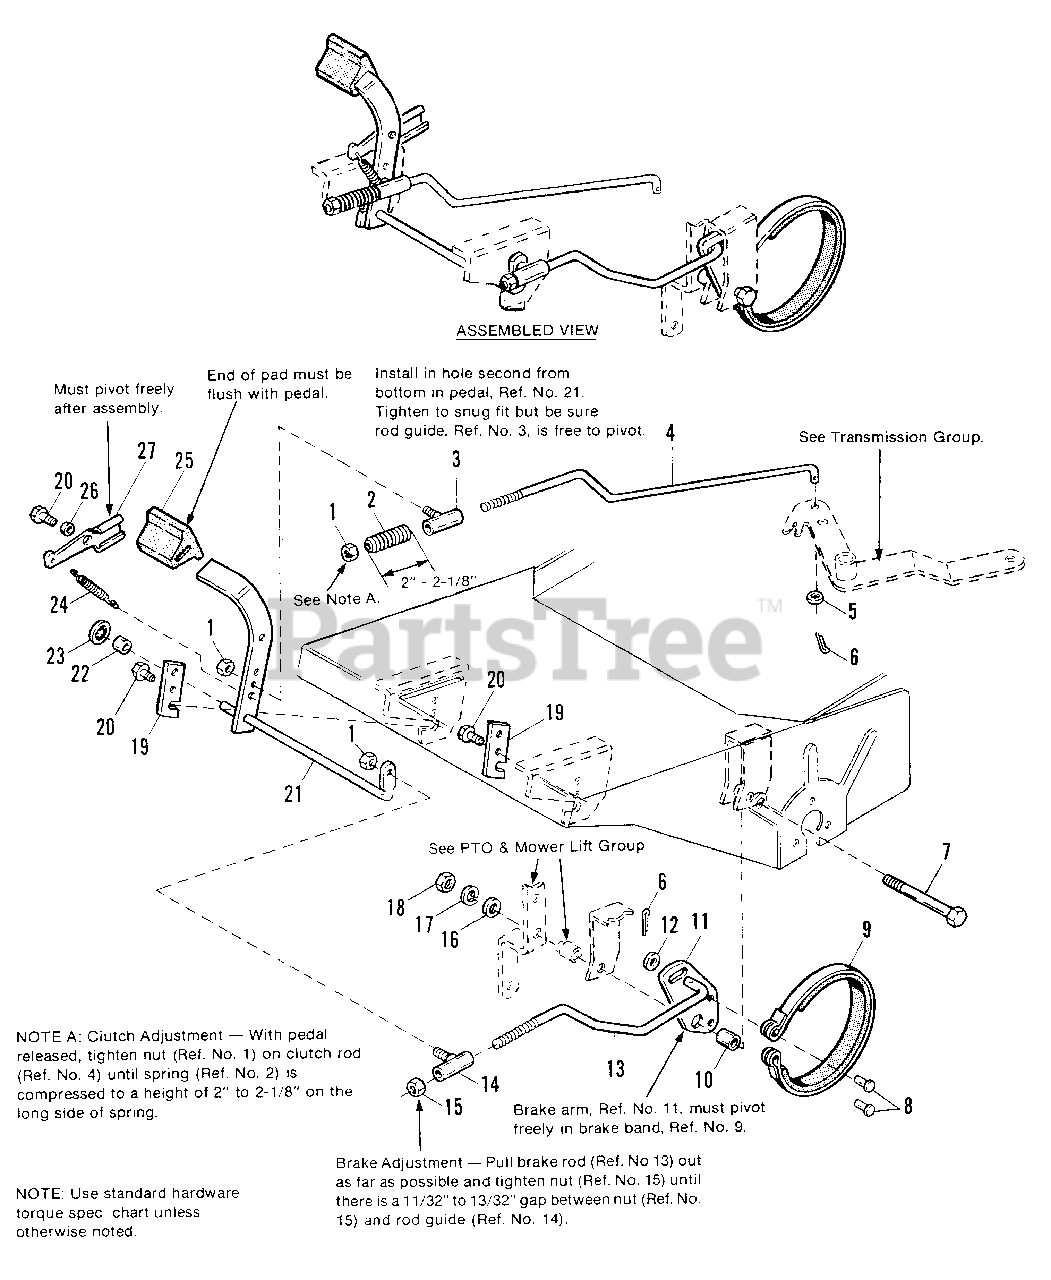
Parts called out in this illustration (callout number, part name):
1	NUT, Hex Lock, 5/16-18
3	GUIDE ASSY., Rod
4	ROD, Clutch
5	WASHER, 11/32 x 3/4
6	PIN, Cotter, 3/4
7	CAPSCREW, 1/2-13 x 3-1/2, Gr. 5
9	BAND ASSY., Brake
11	LINK, Brake Arm
12	WASHER, 3/8
13	ROD, Brake
14	GUIDE ASSY., Rod
15	NUT, Hex Lock, 3/8-16
16	WASHER, 1/2
17	LOCKWASHER, 1/2
18	NUT, Hex, 1/2-13
19	BRACKET, Brake
20	SCREW, Taptite, 5/16-18 x 1/2
21	SHAFT ASSY., Brake
27	LATCH, Brake
